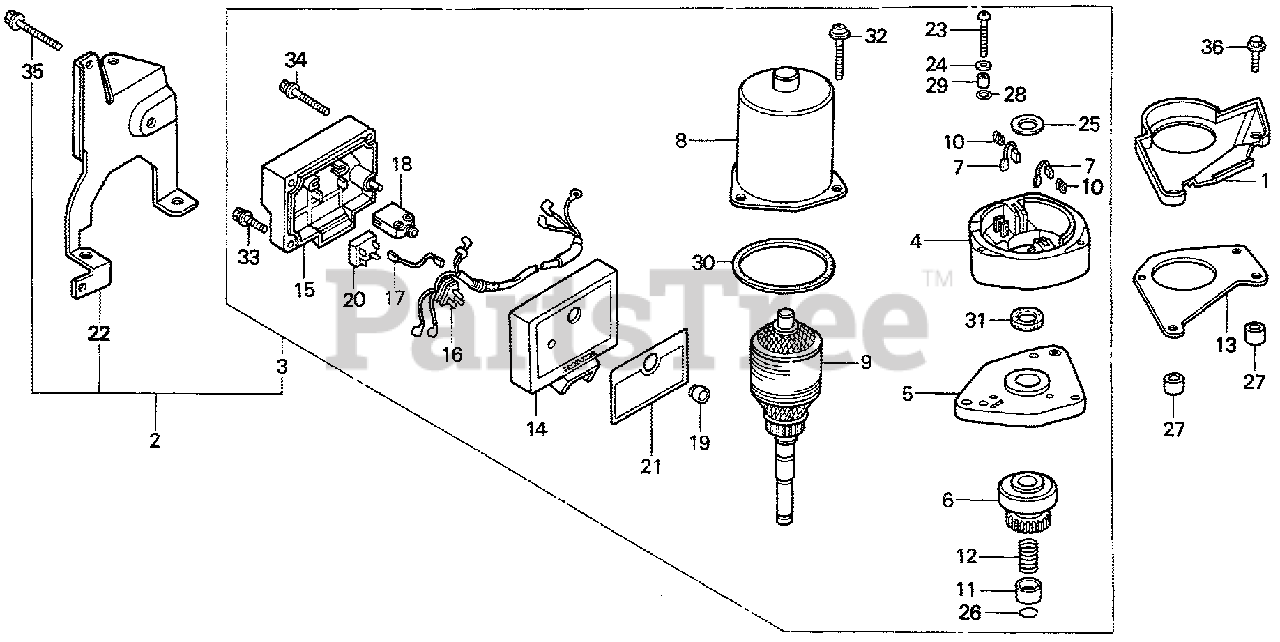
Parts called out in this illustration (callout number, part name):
1	PLATE, SIDE
2	MOTOR ASSY., STARTER (A.C.)
3	MOTOR ASSY., STARTER
4	HOUSING, CENTER
5	HOUSING, PINION
6	CLUTCH
7	BRUSH
8	YOKE
9	ARMATURE
10	SPRING, BRUSH RETURN
11	STOPPER, PINION
12	SPRING, COIL
13	BRACKET, STARTER MOTOR
14	COVER
15	CASE
16	WIRE
17	SUB-WIRE
18	SWITCH, STARTER (Honda Code 2299584). (A.C. 380V-16A)
18	SWITCH, STARTER (Honda Code 2773141). (A.C. 250V-16A)
19	CAP
20	DIODE
21	PLATE, CAUTION (Honda Code 2695054). (ENGLISH/FRENCH)
22	BRACKET, SWITCH BOX
23	SCREW, TRUSS (4X30)
24	WASHER, STAR (4MM)
25	WASHER B
26	RING, RETAINING
27	PIN A, DOWEL (10X14)
28	O-RING
29	COLLAR
30	GASKET
31	OIL SEAL
32	SCREW-WASHER (5X40)
33	SCREW-WASHER (4X20)
34	SCREW-WASHER (4X30)
35	BOLT, FLANGE (6X40)
36	BOLT, FLANGE (8X28)
